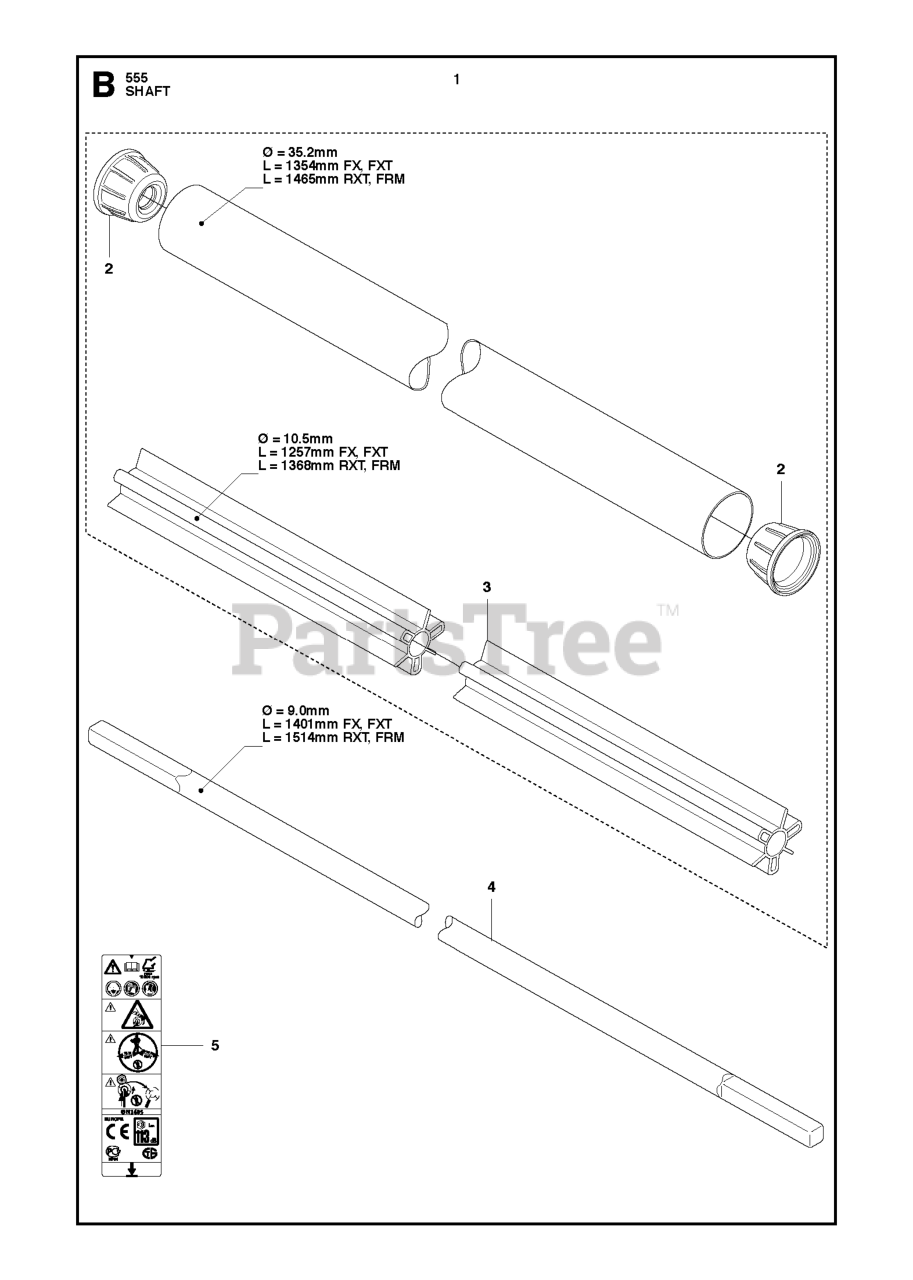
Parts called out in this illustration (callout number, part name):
1	TUBE DRIVESHAFT ASSY
2	RP SPACER
3	BEARING SHAFT
4	DRIVE SHAFT
5	LABEL WARNING TRIMMERS AND BRU
